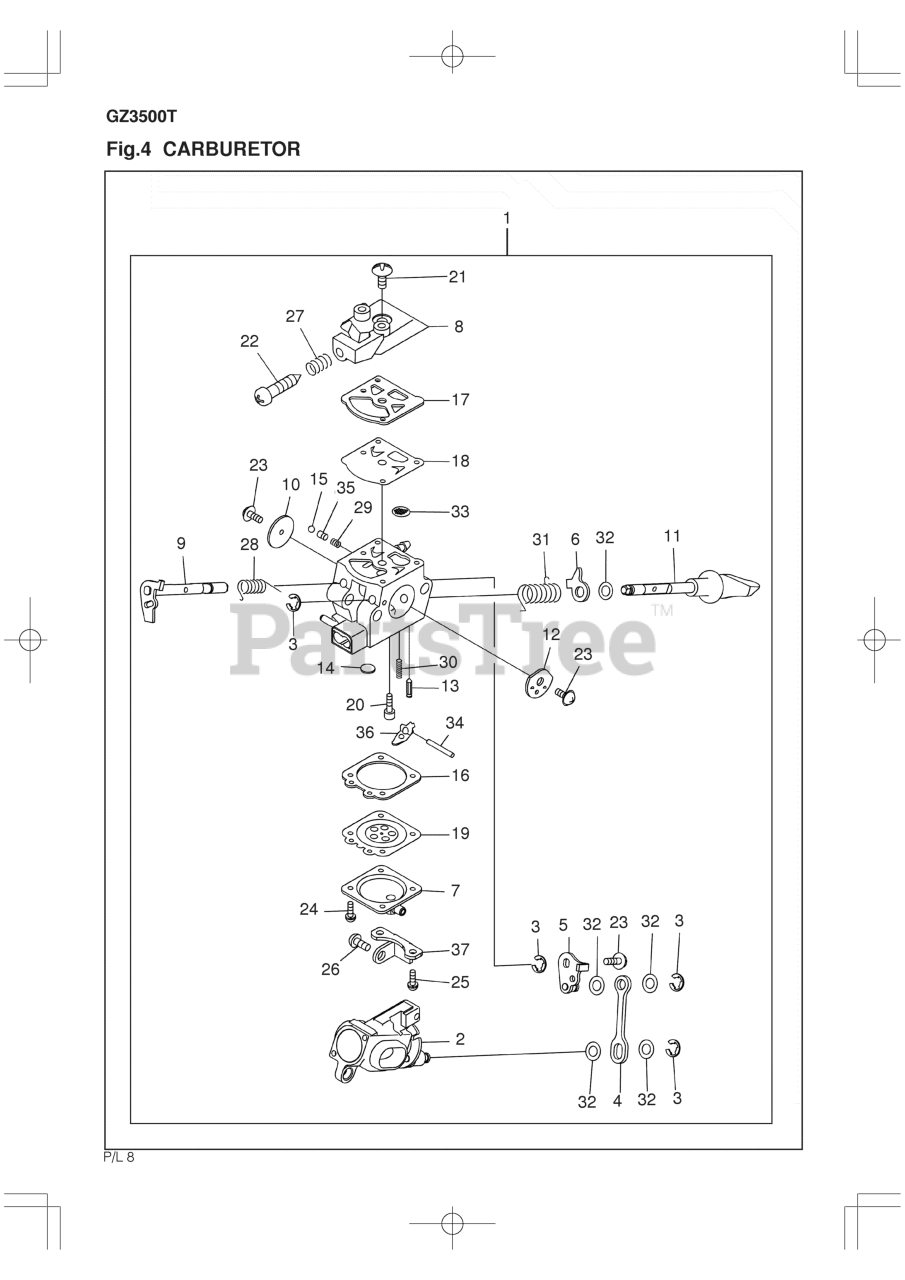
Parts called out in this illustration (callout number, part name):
1	CARBURETOR ASSY
2	BODY ASSY AIR V
4	ROD, LINK
5	LINK ASSY THROT
6	LEVER
7	COVER
8	COVER
9	SHAFT ASST THRO
11	SHAFT ASSY CHOKE
12	VALVE, CHOKE
13	VALVE, INLET
17	GASKET, PUMP
18	KIT ONLY
19	DIAPHRAGM
22	SCREW
24	SCREW ASSEMBLY
25	SCREW ASSY
26	SCREW
27	SPRING, IDLE
28	SPRING, RETURN
31	SPRING
32	WASHER
34	PIN
36	LEVER
37	BRACKET
